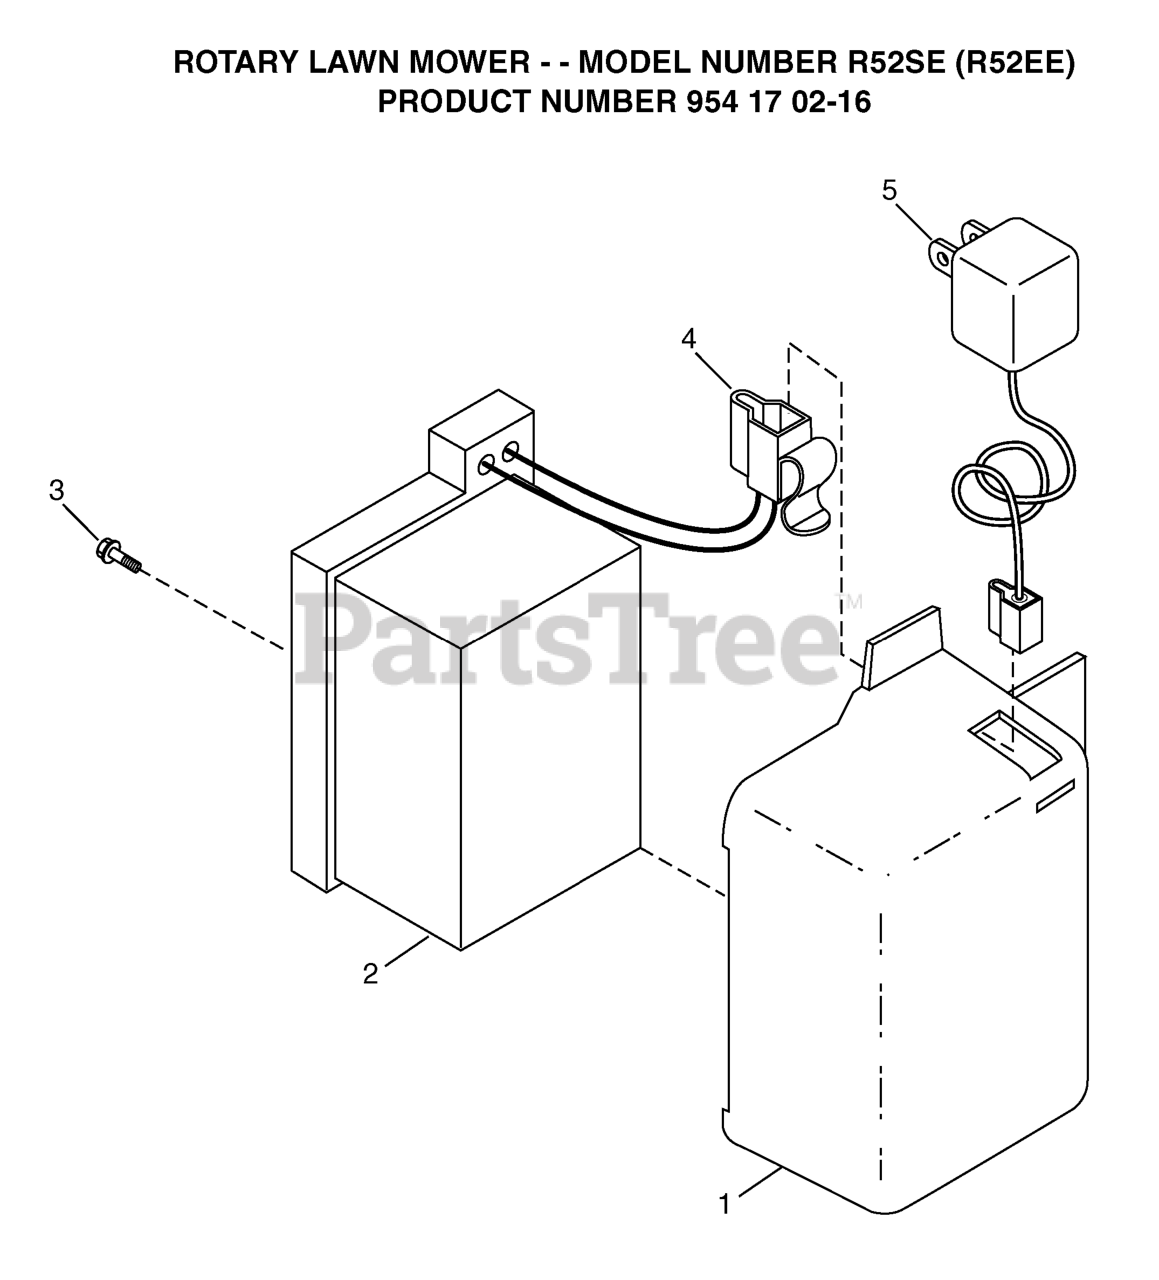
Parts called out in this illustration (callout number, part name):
2	KIT BATTERY REPL
3	SCREW.HX.13X.750
4	CONNECTOR PM
5	BATTERY CHARGER
